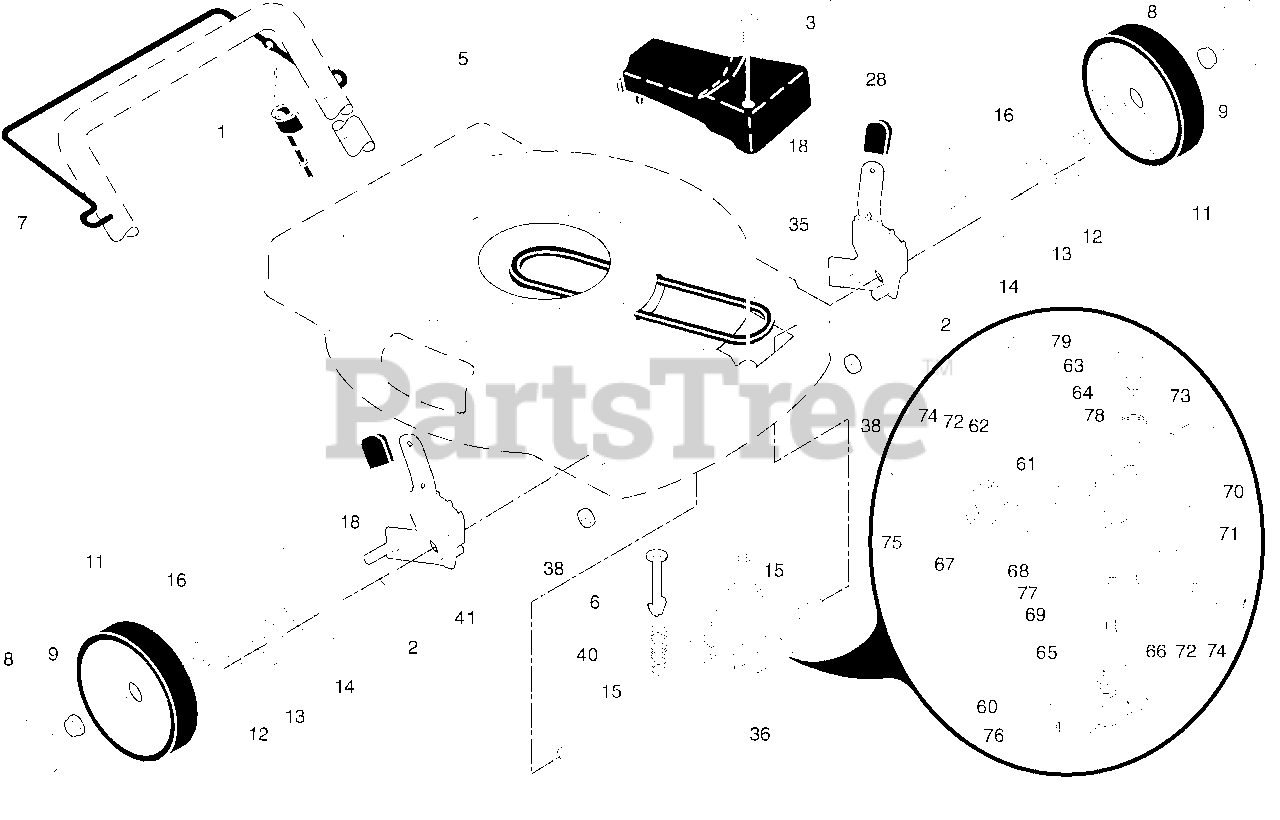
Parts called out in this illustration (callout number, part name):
1	Drive Control Cable Assembly
2	Bearing, Wheel Adjuster
3	Pan Head Tapping Screw #10-24 x 2-3/4
6	Spring Retainer
7	Control Bar, Drive
8	Hubcap
9	Locknut, Hex
11	Wheel & Tire Assembly
12	E-Ring
13	Pinion
14	Dust Cover
15	Pawl, Drive
16	Washer
18	Selector Knob
28	Drive Cover
35	Kit, Wheel Adjuster, LH
36	Gear Case Assembly, Complete
38	Locknut, Hex 1/4-20
40	Spring
41	Kit, Wheel Adjuster, RH
60	Case, Lower
61	Case, Upper
62	Gear, 27 Teeth
63	Lever, Clutch
64	Spring, Return
65	Shaft, Input
66	Dog, Movable
67	Dog, Fixed
68	Wire, Formed
69	Bearing, Ball
70	Fork, Shift
71	Seal, Output Shaft
72	Washer
73	Seal, Case
74	Bushing
75	Shaft, Output
76	Screw
77	Seal, Input Shaft
78	Pulley, Drive
79	Locknut, Hex
